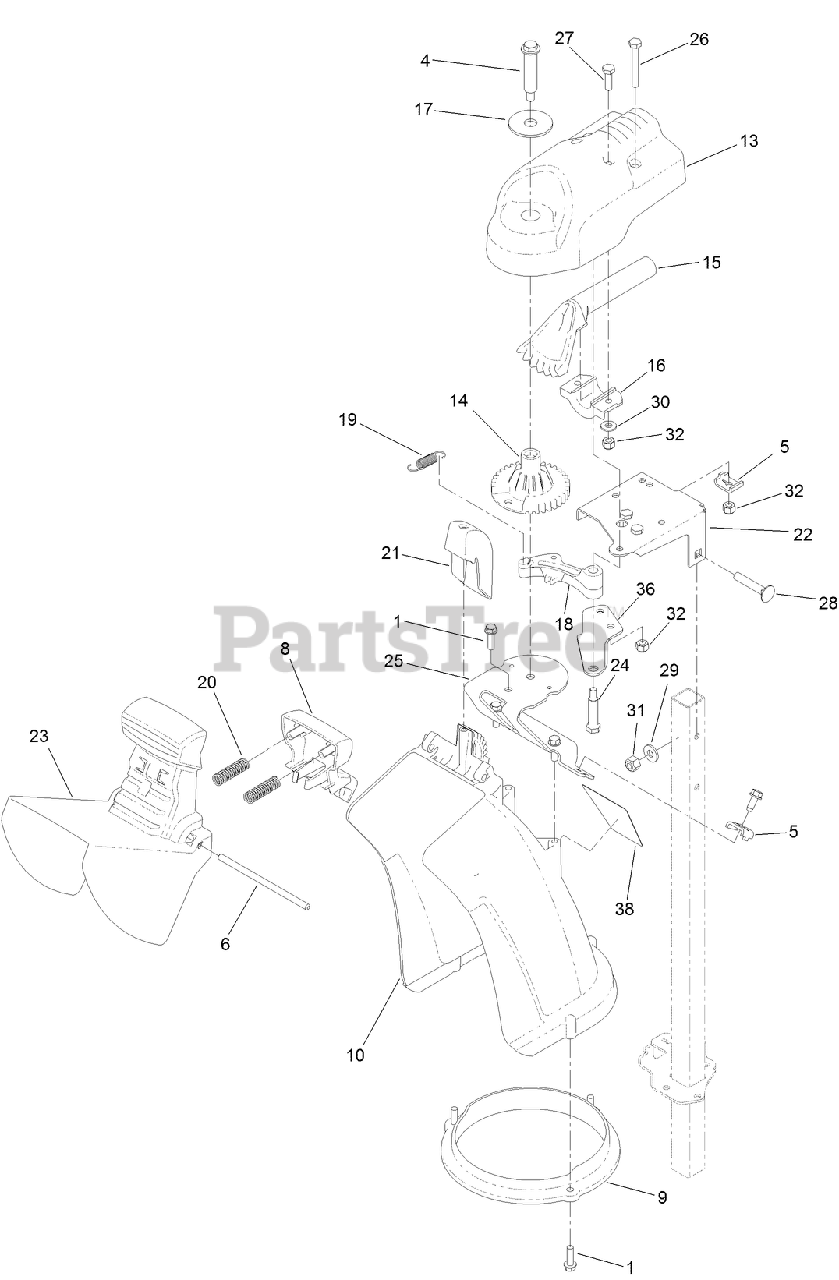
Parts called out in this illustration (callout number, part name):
1	SCREW-HWH
4	BOLT-SHOULDER
5	CLAMP-CABLE
6	HINGE PIN-DEFLECTOR
8	TRIGGER-DEFLECTOR
9	RING-CHUTE
10	CHUTE-DISCHARGE
13	MOUNT-CHUTE, DISCHARGE
14	GEAR-CHUTE
15	GEAR-BEVEL
16	MOUNT-GEAR, BEVEL
17	WASHER-FLAT
18	LATCH-CHUTE
19	SPRING, CHUTE LATCH
20	SPRING-COMPRESSION
21	CHUTE-COVER
22	BRACKET-SUPPORT, CHUTE
23	DEFLECTOR-CHUTE
24	BOLT, SHOULDER
25	BRACKET-MOUNT, CHUTE
26	SCREW-HH
27	SCREW-HH
28	BOLT-CAR
29	WASHER-FLAT
30	WASHER-FLAT
31	NUT-LOCK, NI
32	NUT-LOCK, NI
36	BRACKET-SUPPORT, LATCH
38	DECAL-GUARANTEE
